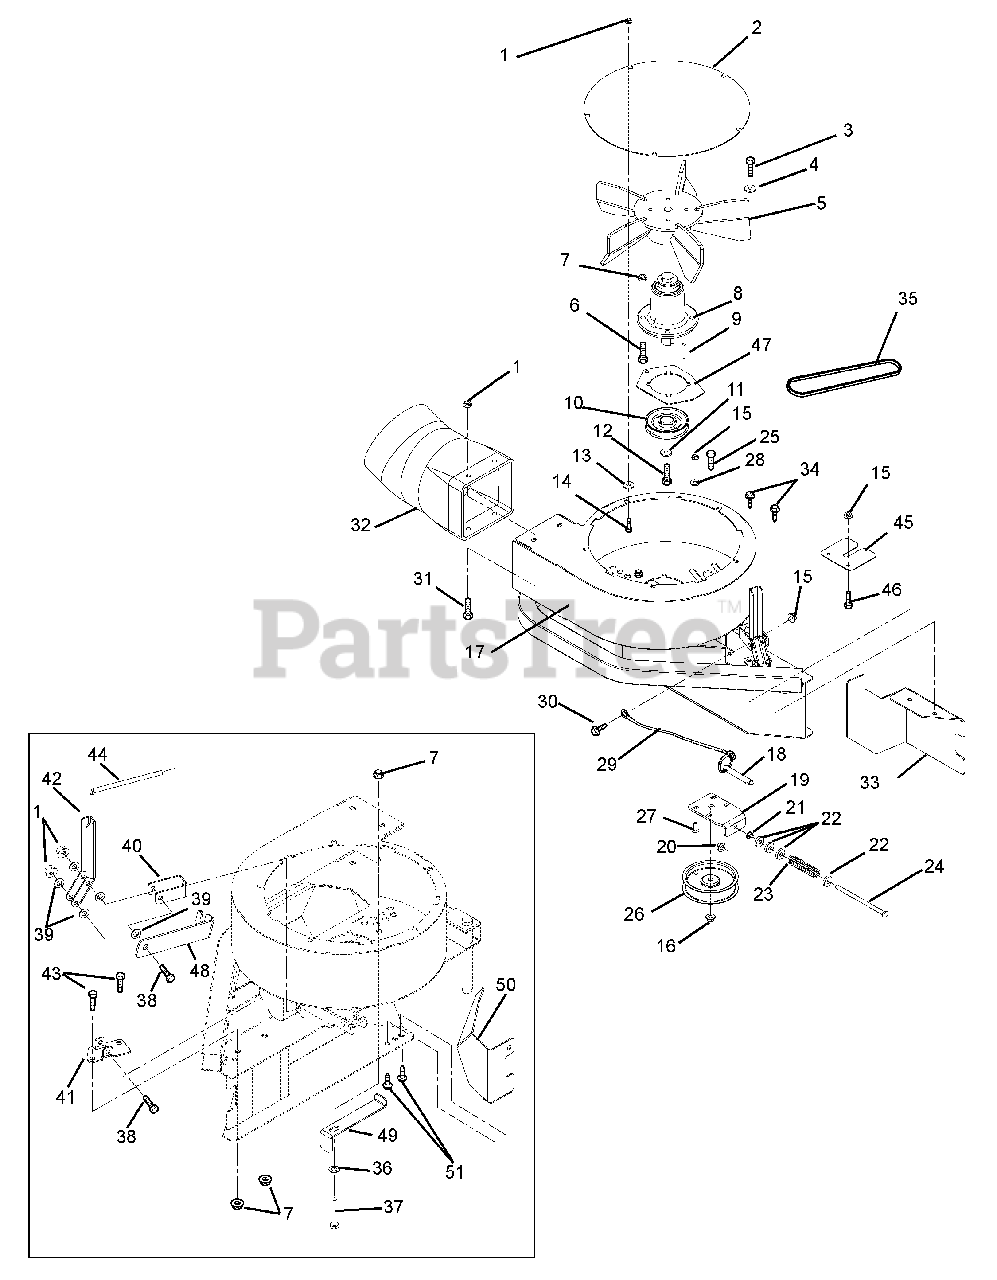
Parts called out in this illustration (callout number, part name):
1	Nut, .31-18 Nyloc Flange
2	Cover, Blower
3	Bolt, Hex .62-18 x 1.75
4	Washer, Bevelled .63 x 1.625 x .14
5	Weldment, Impeller
6	Bolt-Hex .38-16 x 1.25 Grade 5
7	Nut, .38-16 Nyloc Flange
8	Maintenance Free Spindle Assembly
9	Key, Square .25 x .25 x 1.00 RC 40-50
10	Weldment, Pulley-V 3.50 x 1.004 with Key
11	Washer, Flat Steel .39 x 1.5 x .125
12	Bolt, Hex .38-16 x 1.00 EP30
13	Nut-Push .312
14	Bolt, Round Head Square Short Neck .31-18 x .75 Grade
15	Nut, Locking-Top-Flange .25-20
16	Nut, .38-16 Nyloc Flange
17	Weldment, Blower Housing
18	Pin, Spring Ball .375OD x 1.50
19	Bracket, Adjustable Idler
20	Nut, .31-18 Nyloc Flange
21	Nut-Spin Lock-Flange .312-18
22	Washer, Flat Steel .38 x .87 x .179
23	Spring, Compression .092 x .77 x 3.13
24	Bolt, Hex .31-18 x 5.50 Grade 5
25	Bolt, Hex .38-16 x 1.75 Grade 5
26	Pulley, Idler 4.00
27	Bolt, Round Head Square Neck .25-20 x .75 Grade 5
28	Bushing-Flange .265 x .437 x .250 x .750
29	Cable, Hood
30	Bolt, Hex .25-20X.75 Grade 5
31	Bolt, Hex .31-18X.75 Grade 5
32	Adapter, Hose
33	Baffle, Blower 52"
34	Screw, Tapping .38-16 x .50 Hex Washer Head
35	V-Belt, 72" Mower Deck
36	Washer, Flat - Steel .406 x .812 x .065
37	Bolt, Hex .38-16 x 1.00 Grade 5
38	Bolt, Hex .31-18 x 2.00 Grade 5
39	Washer, Flat-Nylon .375 x .75 x .060
40	Link, Idler Release
41	Mount, Idler Release Lever
42	Lever, Idler Release
43	Bolt, Hex .38-16 x .75 Grade 5
44	Bolt, Hex .31-18 x 5.50 Grade 5
45	Finger Guard 52-Inch Deck
46	Bolt, Hex .25-20 x .50 Grade 5
47	Plate, Bearing Housing Support
48	Lock, Idler Release Lever
49	Finger, Belt
50	Baffle, Blower Rear 52"/60"
51	Screw, Tapping .38-16 Hex Washer Head Thread Rolling
